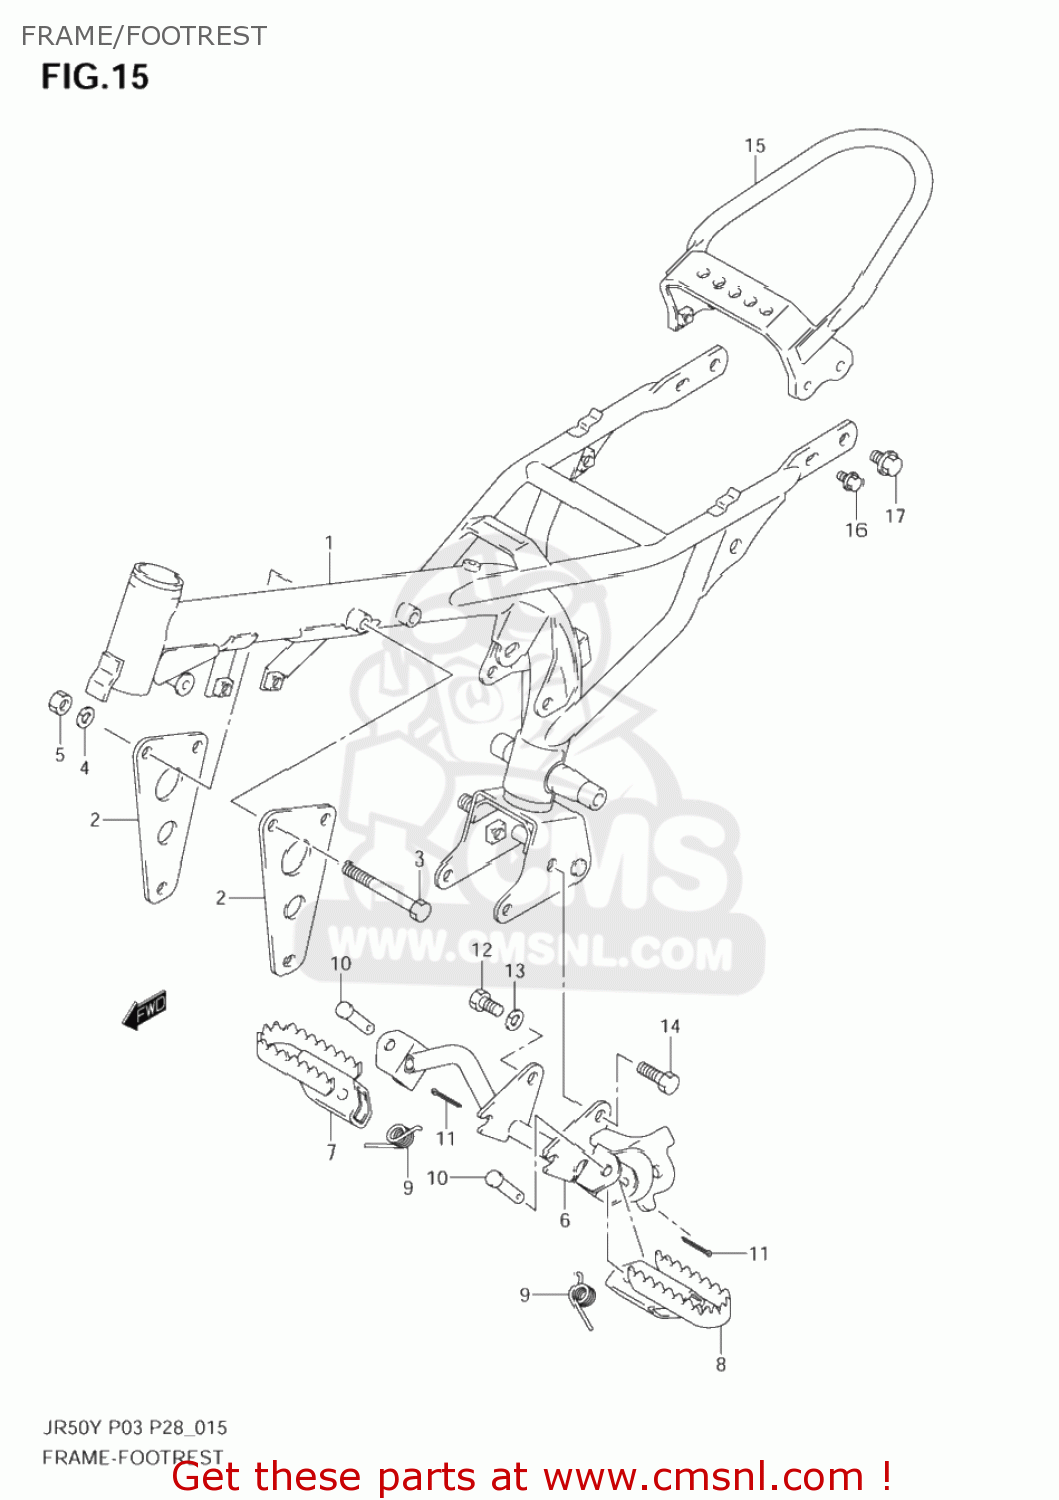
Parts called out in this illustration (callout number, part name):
1	FRAME(BLACK)
2	PLATE,ENG MTG
3	BOLT
4	LOCK WASHER
5	NUT
6	BAR,FR FOOTREST
7	FOOTREST,FR,R
8	FOOTREST,FR,L
9	SPRING
10	PIN
11	PIN
12	BOLT
13	LOCK WASHER
14	BOLT(8X14)
15	GRIP,RR
16	BOLT
17	BOLT
